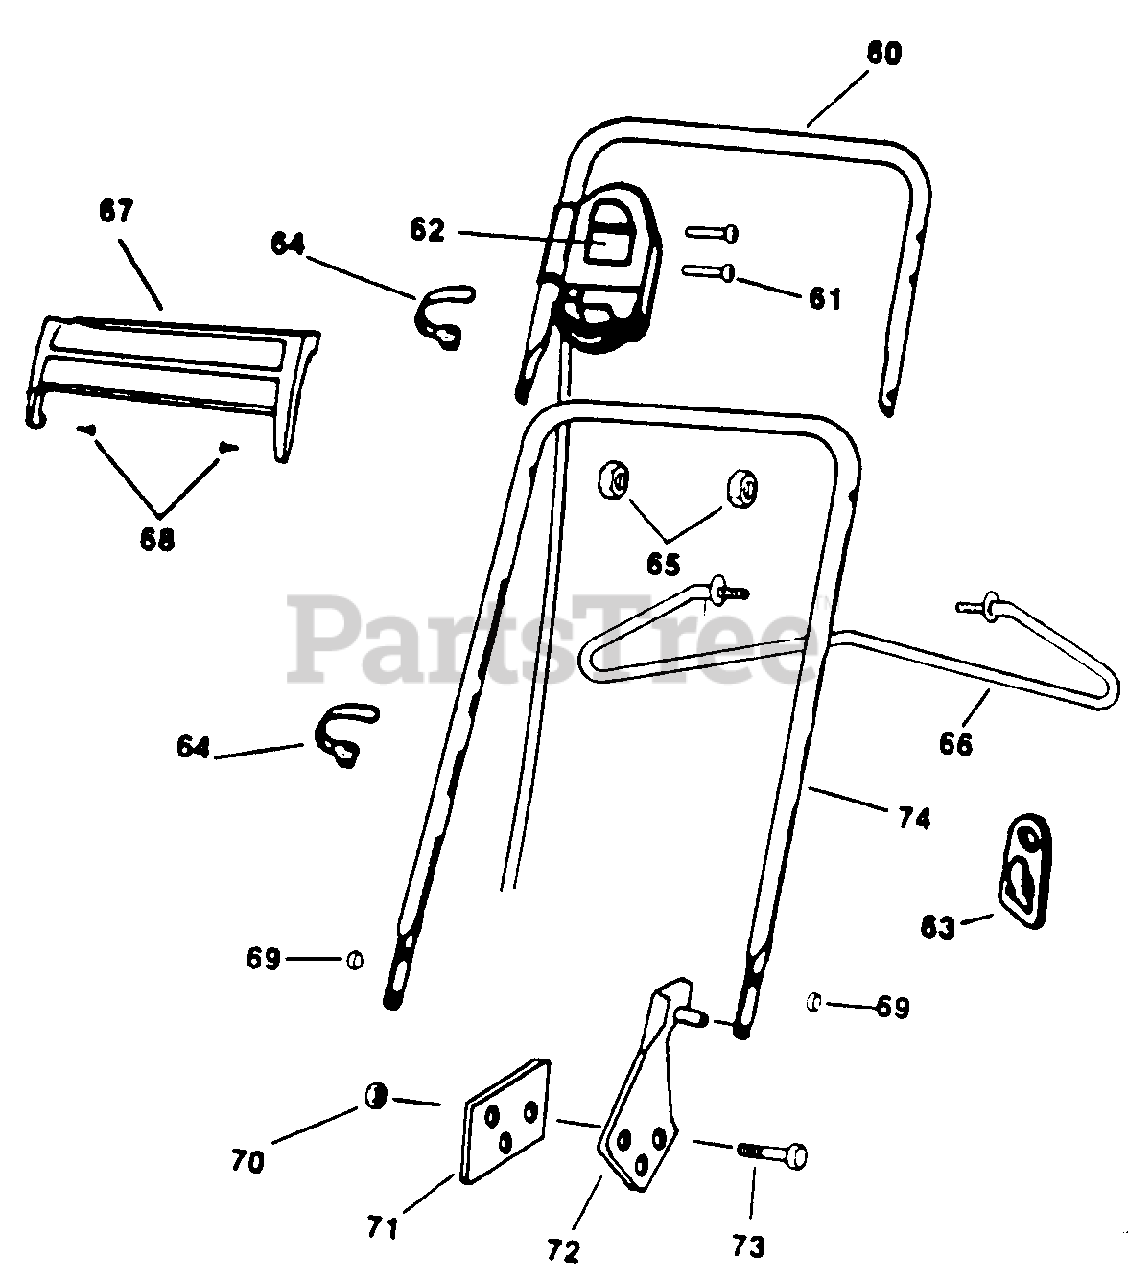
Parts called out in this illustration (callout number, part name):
60	Upper Handle
61	Screw #7-19 x 1" Thread Forming
62	Label-Switch Box
63	Strain Relief
64	Plastic Tie
65	Lock Nut 1/4-20 Hex Flange
66	Cord Control Rod
67	Trim Panel
68	Screw #10 x 3/4" Tapping
69	Cotter Pin 3/32 x 1/2"
70	Hex Nut 5/16-18 Locking
71	Nut Plate
74	Lower Handle
